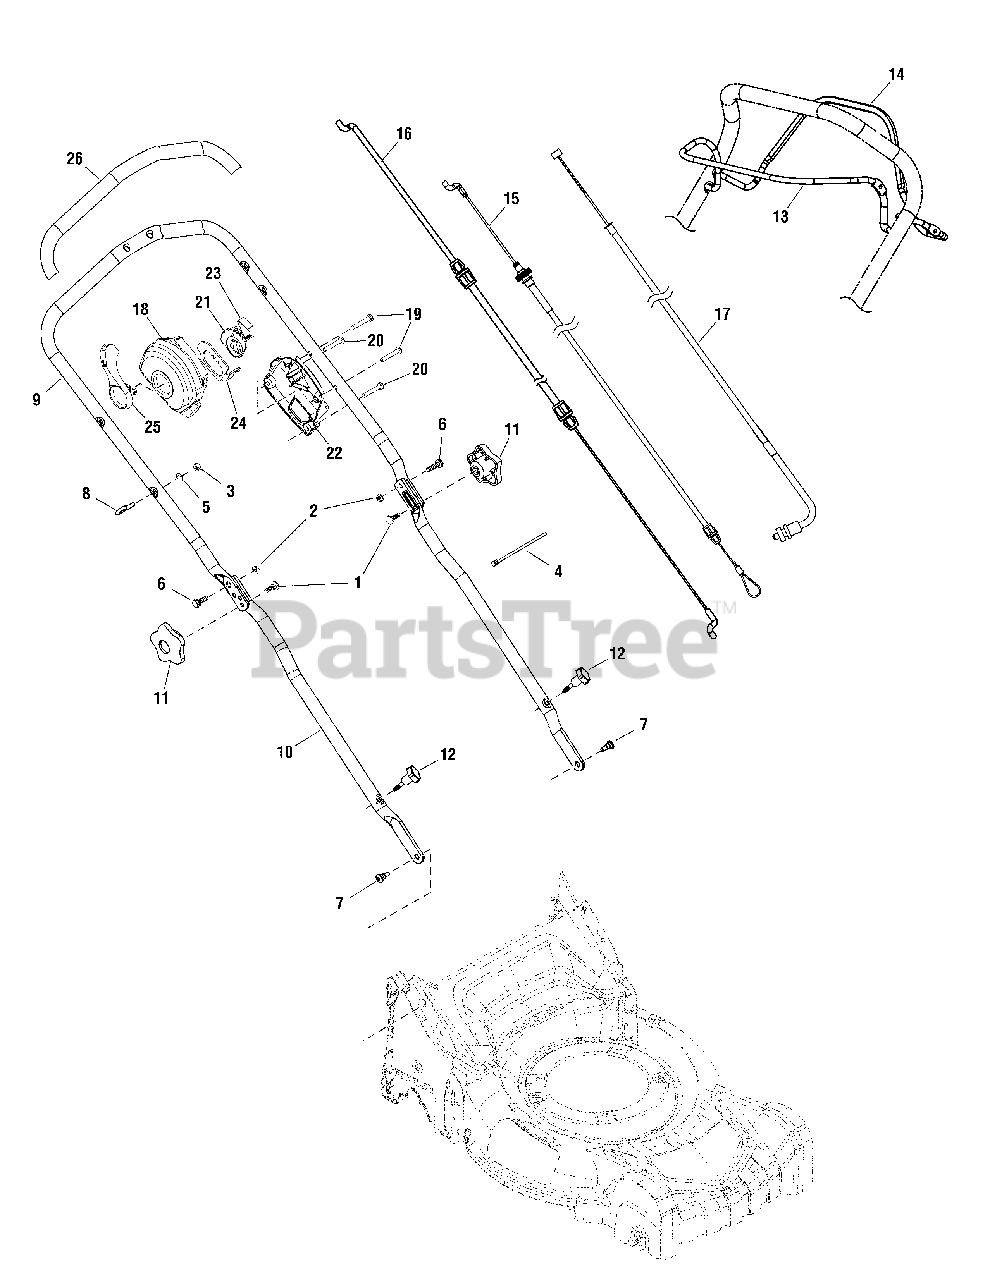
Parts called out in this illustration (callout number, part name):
1	BOLT, 5/16-18 x 1 G5
2	NUT, Nylock Flanged, 1/4-20
3	NUT, Nylock, M6
4	CABLE CLIP
5	WASHER, A6.4
6	SCREW, 1/4-20
7	BOLT, Shoulder
8	BOLT, Eye
9	HANDLE, Upper
10	HANDLE, Lower
11	WING KNOB, 5/16-18
12	WING KNOB
13	BAIL, Control
14	BAIL, Drive
15	CABLE, Drive
16	CABLE, Control
17	CABLE, Speed Select
18	CONTROL HOUSING, Upper
21	SPEED ACTUATOR
22	CONTROL HOUSING, Lower
23	SPRING, Shift
24	RACK PLATE
25	LEVER, Speed Select
